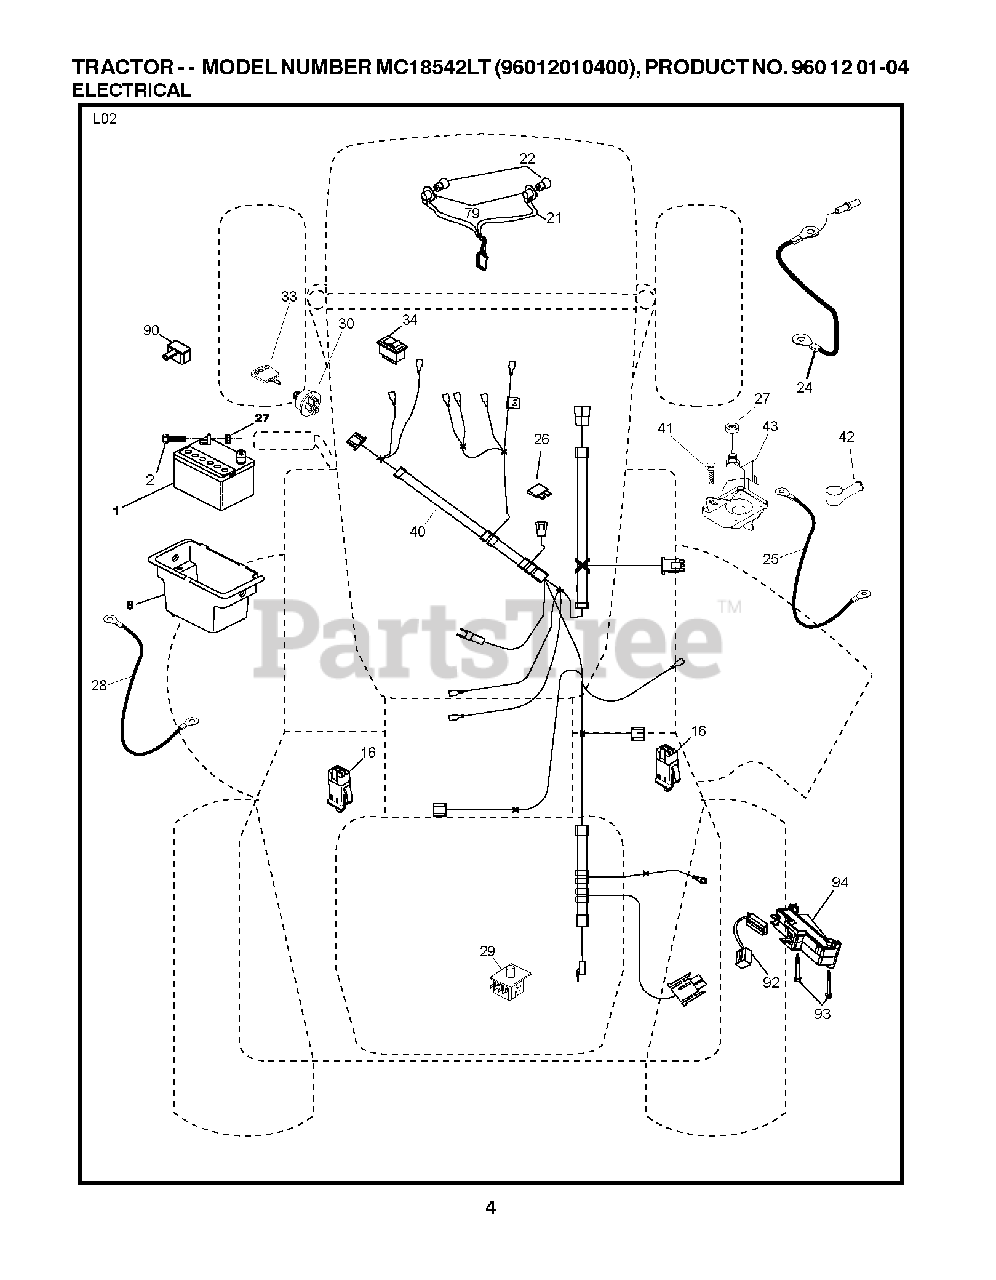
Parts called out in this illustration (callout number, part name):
1	REPL BY 532 12 38-99
2	BOLT.HEX.1/4.X.3/4.DICHROMATE
8	BOX.BATTERY.FENDER
16	SWITCH INTERLOOK PUSH-IN
21	HARNESS.W/LIGHT SOCKET
22	LIGHTBULB
24	CABLE.STARTER.6GA.11"RED
25	CABLE.GROUND.REAR.BTRY.8GA.44"
26	FUSE 20AMP
27	NUT
28	CABLE GROUND 6 GA. 12" BLACK
29	SWITCH.SEAT.DP W/RAMPS
30	SWITCH.IGN.DELTA.W.LGH.ROS
33	KEY.CHAIN.BLISTER.PACK.GEN.INT
34	SWITCH LT
40	HARNESS.IGN.CABLE.REG.
41	BOLT
42	TERMINAL COVER
43	SOLENOID.W/BRASS.PLUNGER
79	BULB HOLDER ASM.
90	COVER.TERMINAL.BATTERY
92	HARNESS.PIGTAIL.CONSLE
93	SCREW.PLASTITE
94	MODULE.REVERSE.ROS
